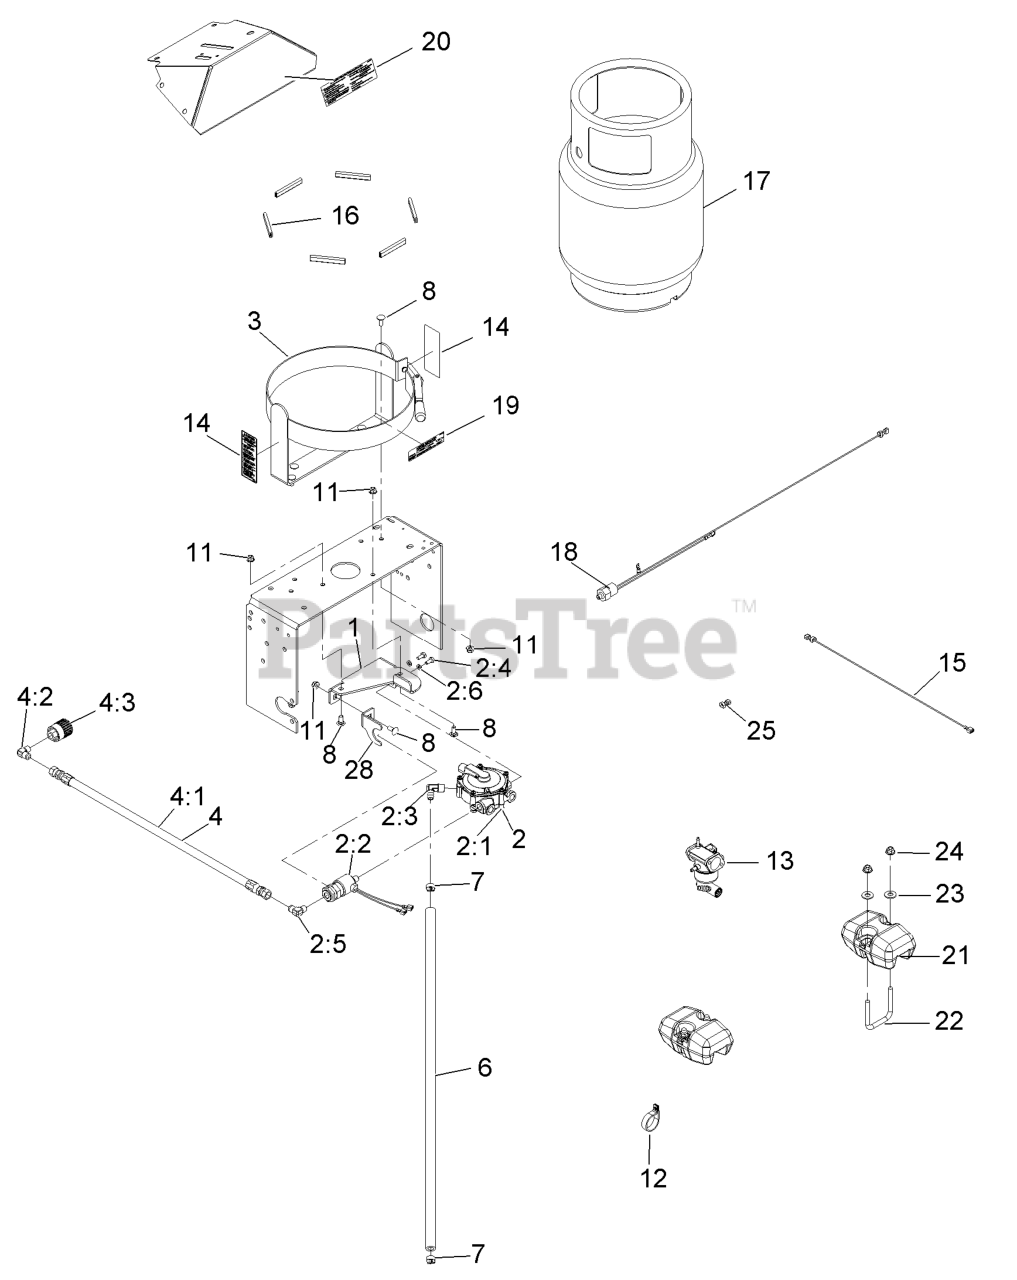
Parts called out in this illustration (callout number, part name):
1	REGULATOR MOUNT-THP
2	Asm, Reg And Shutoff
2:1	Regulator-Lp, T60
2:2	ASM, LPG FUEL SHUTOFF W/T
2:3	ELBOW-90 DEG
2:4	SCREW-HH
2:5	ELBOW 90DEG,1/4 NPT X3/8
2:6	WASHER-LOCK
4	Asm, Lpg Fuel Hose
4:2	ELBOW 90DEG,1/4 NPT X3/8
4:3	CONNECTOR-LPG TANK, LH TH
6	HOSE,LP 1/2 X 33
7	CLAMP-HOSE
8	BOLT-CARR
11	NUT-HF, NI
12	CLIP-LOOM
13	MIXER ASM, KA FS600V
14	DECAL-LPG WARNING
15	ASM, WIRE 20"
16	STRIP-SEAL
19	DECAL,LPG TANK SPEC VERTI
20	DECAL-TANK REPLACEMENT
21	WEIGHT-SUPPORT, CASTER
23	WASHER-FLAT
24	NUT-HF, NI
25	RECEPTICAL -FEM, .250, IN
28	SOLENOID SUPPORT
